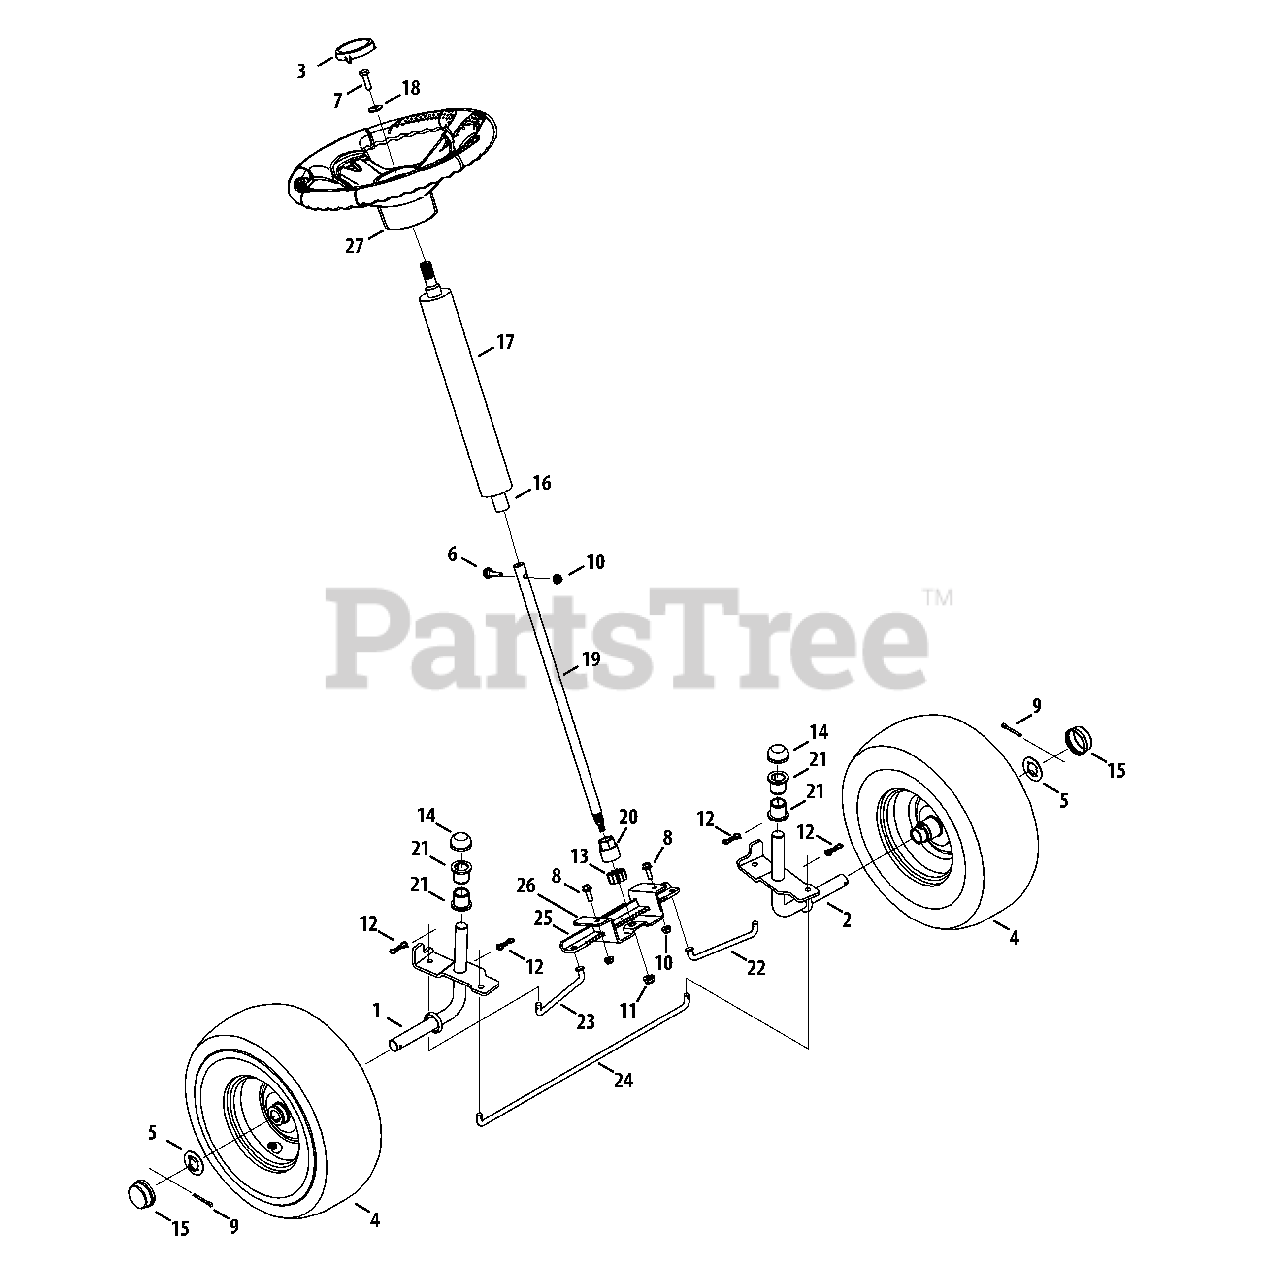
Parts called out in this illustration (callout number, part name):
1	Front Axle Assembly, RH
2	Front Axle Assembly, LH
3	No Sprig Cap
4	Complete Wheel Assembly
5	Washer, .781 x 1.59
6	Shoulder Screw, .375 x .148 x 1/4-20
7	Hex Head Screw, 5/16-18:1.00
8	Carriage Screw, 1/4-20, .62
9	Cotter Pin, 5/32 x 1.25
10	Flange Lock Nut, 1/4-20
11	Flange Lock Nut, 3/8-16
12	Bow-Tie Cotter Pin, 72
13	Steering Pinion Gear
14	Push Cap, 3/4
15	Hub Cap
17	Steering Sleeve
18	Bevel Washer, .340X.872X.060
19	Steering Shaft, .625 OD X 18.03
20	Hex Flange Bearing, 5/8
21	Flange Bearing, .760 X .941 X 1.0
22	Steering Rod, LH
23	Steering Rod, RH
24	Front Tie Rod
25	Steering Rack Plate
26	Lower Steering Bearing
27	Steering Wheel, Std. Grip
